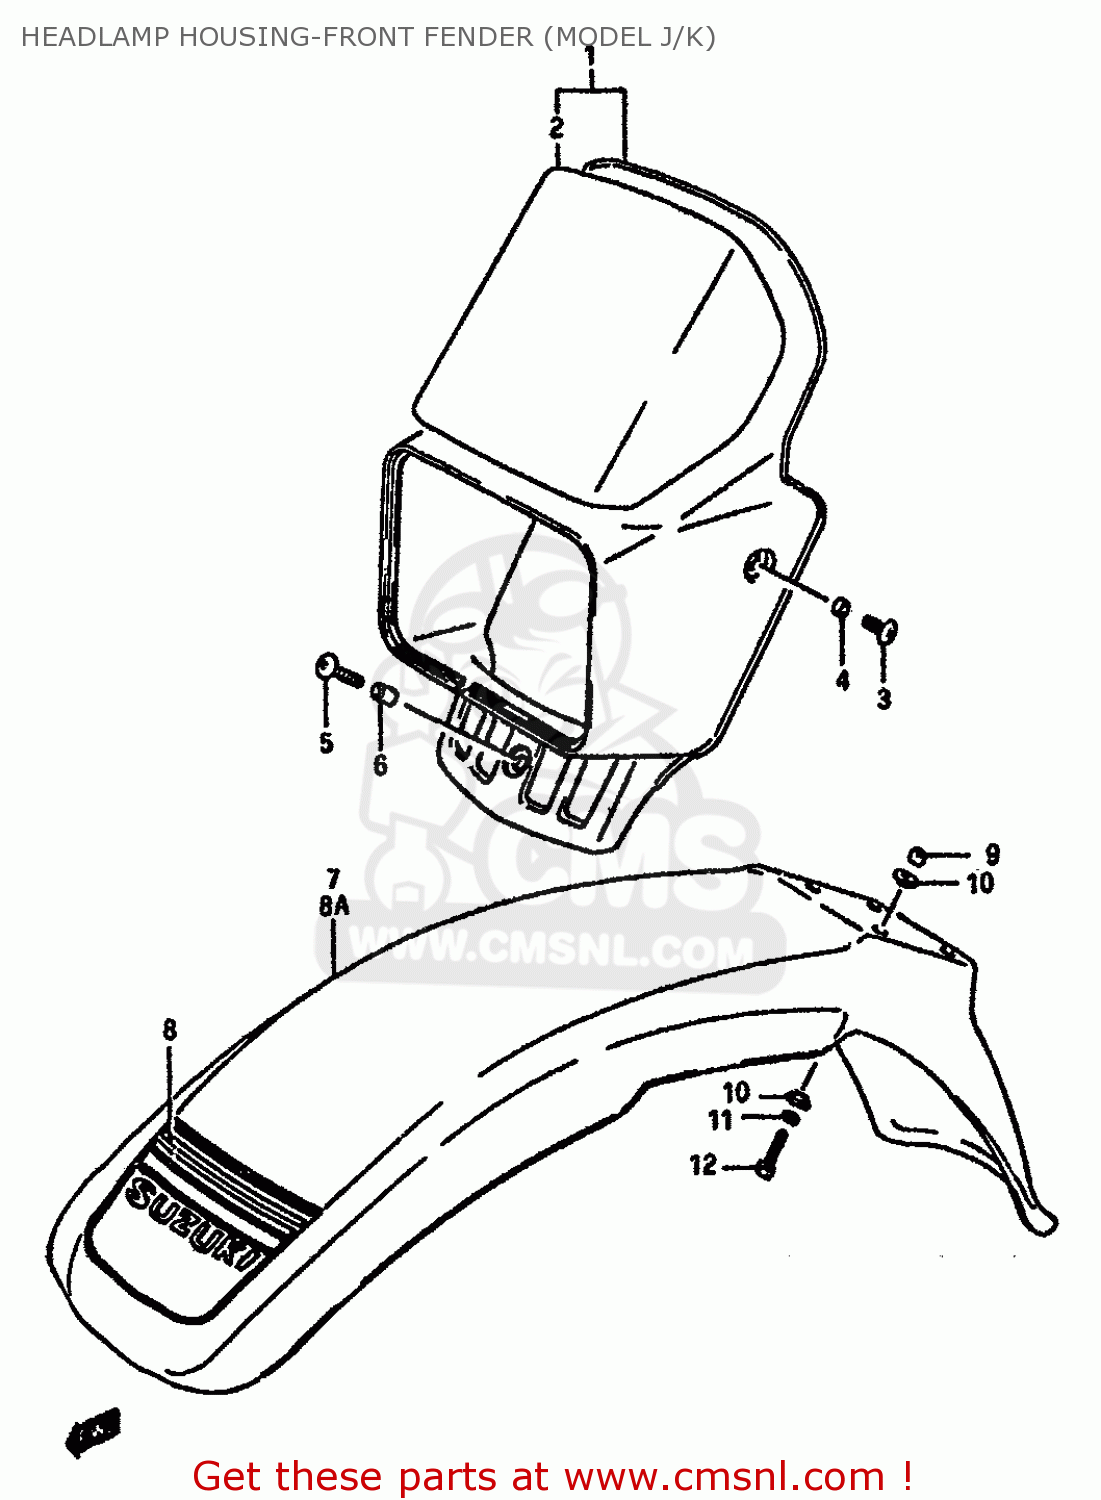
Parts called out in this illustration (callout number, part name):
1	COVER,HEADLAMP
2	TAPE SET (BLUE)
3	SCREW 6X12
4	SPACER (6.1X8X3.5)
5	SCREW, CENTER
6	SPACER (6.1X8X12)
7	FENDER, FRONT (BLUE)
8	TAPE,FR FENDER
8A	FENDER,FRONT
9	SPACER(6.1X9X7.5)
10	WASHER
11	WASHER,LOCK
12	BOLT
13	TAPE SET
14	FENDER, FRONT (BLUE)
15	TAPE SET
16	SPACER(6.1X9X7.5)
17	WASHER
18	WASHER,LOCK
19	BOLT
